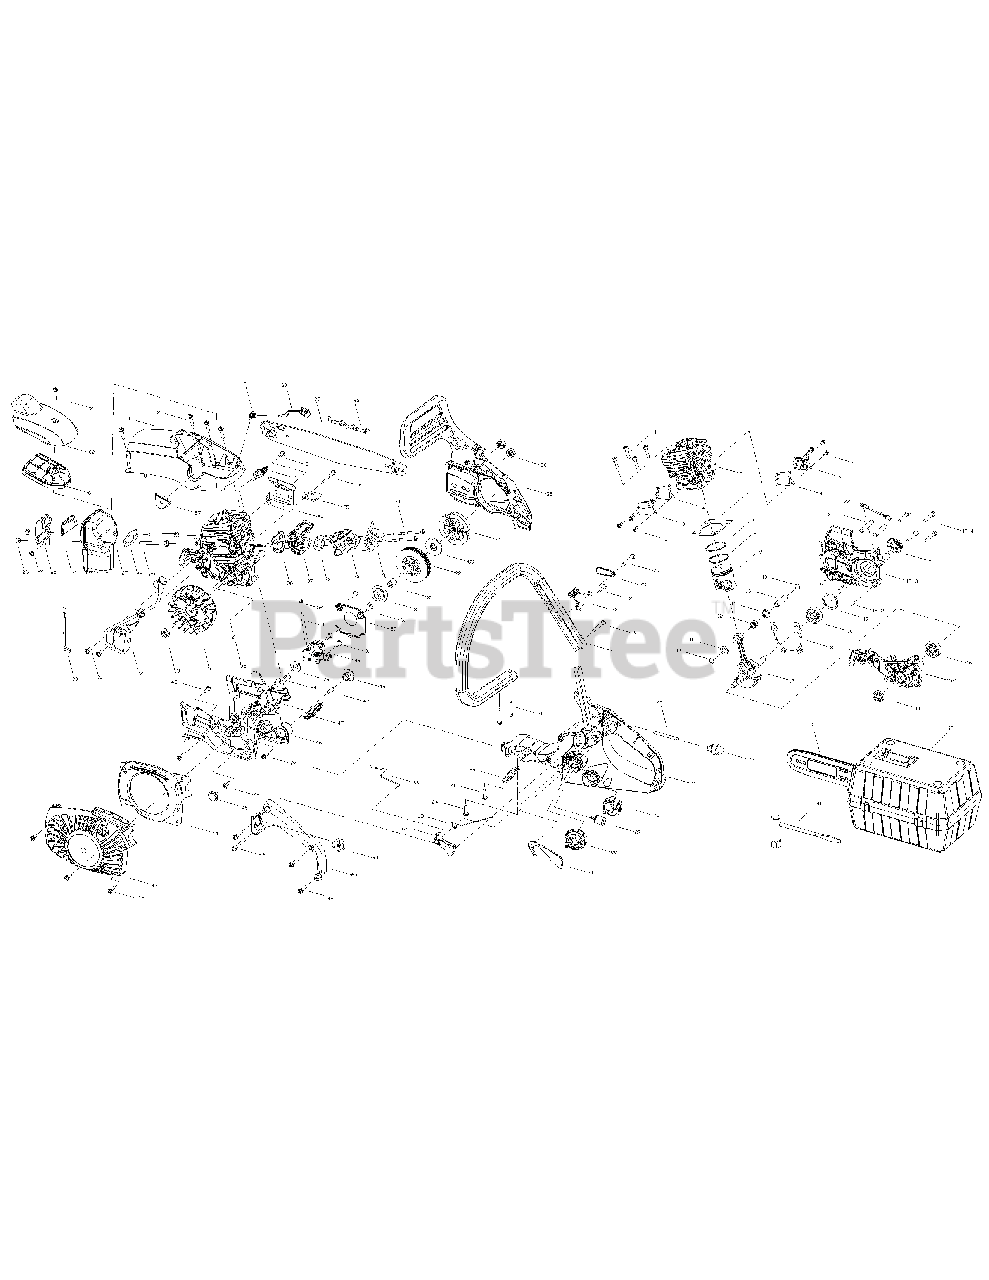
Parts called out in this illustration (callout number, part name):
13	PIN, PISTON
15	CLY CASE ASS’ Y
15-1	CLY CASE, LEFT
15-3	CLY CASE, RIGHT
17	CRANK/ROD ASS’ Y
25	COVER, MESH
26	SPARK ARRESTER
27	MUFFLER ASS’ Y
32	IGNITION ASS’ Y
33	NUT
34	FLYWHEEL ASS’ Y
35	WOODRUFF KEY
37	ISOLATER ASS’Y, CARBURETER
40	AIR GUIDE
42	SCREW
43	STARTER HOUSING ASS’Y
44	CAP, AIRWAY
46	BRACKET ASS’ Y
47	FIXED, PUSH ROD
49	PUMP ASS’Y
50	CAP, ANTI-DUST
53	SPARK PLUG
57	CAP, ADJUST
59	HOLDER, CHOKE LEVER
60	LEVER, CHOKE
61	AIR FILTER ASS.Y
62	TOP COVER
63	HANDLE, LB
67	TRIGGER, THROTTLE
71	HANDLE, FRONT
73	CAP, SPRING
74	TRIGGER, RELEASE
75	OIL CAP ASS’ Y
76	HANDLE ASS’Y (R)
82	DRUM ASS’Y
84	CLUTCH ASS’Y
85	BRAKE KIT ASS’ Y
87	FUEL FILTER
88	FUEL CAP ASS’Y
93	CARRY CASE
